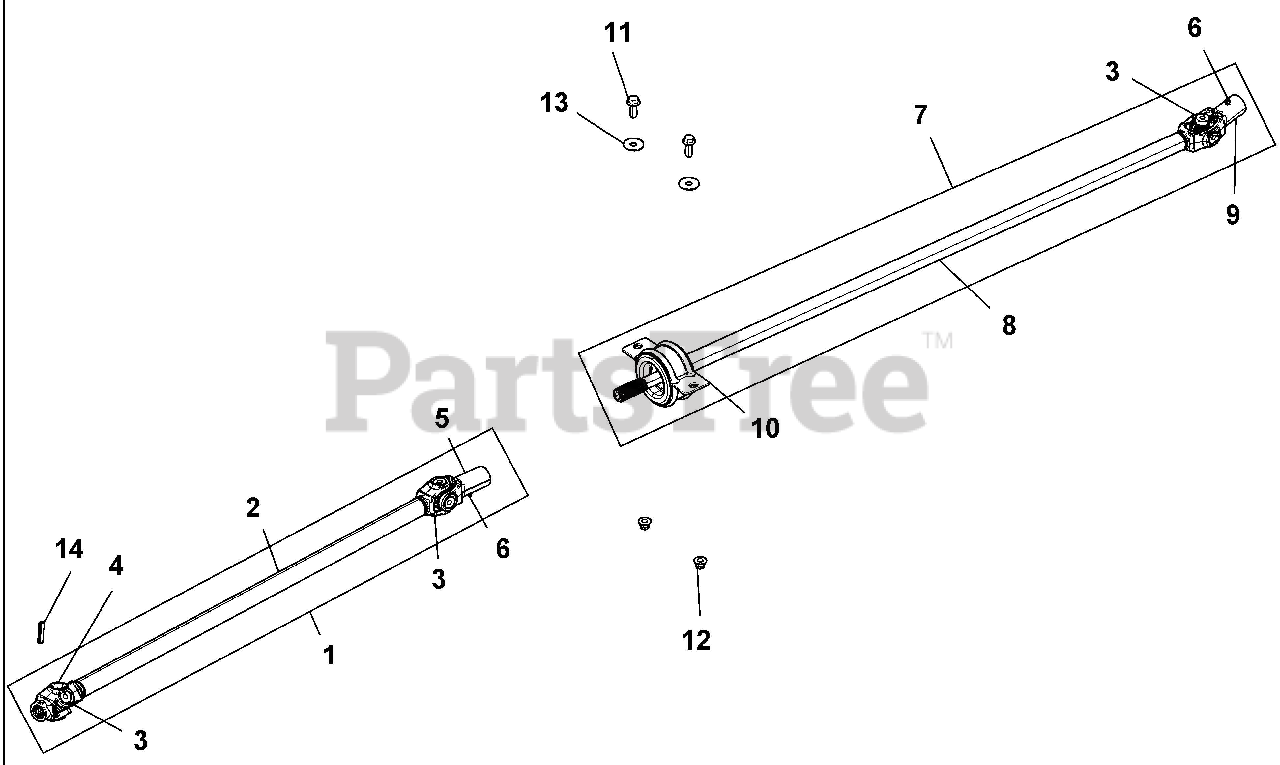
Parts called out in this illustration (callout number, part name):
1	ASM-PROPSHAFT,FRONT
2	WELD-PROPSHAFT,FRONT
3	U-JOINT-1000 SERIES
4	YOKE-PIN
5	YOKE, SLIP, INDEXED
6	FITTING, LUBRICATION
7	ASM-PROPSHAFT,REAR
8	WELD-PROPSHAFT,REAR
9	YOKE-SLIP
10	ASM-BEARING,FLEX
11	SCR-HXFL-M10X1.25X30 8.8 ZOD
12	NUT-M10X1.25,FLG,NYLOC-OLIVE D
13	WASHER, FLAT
14	PIN,SPRING(10)
